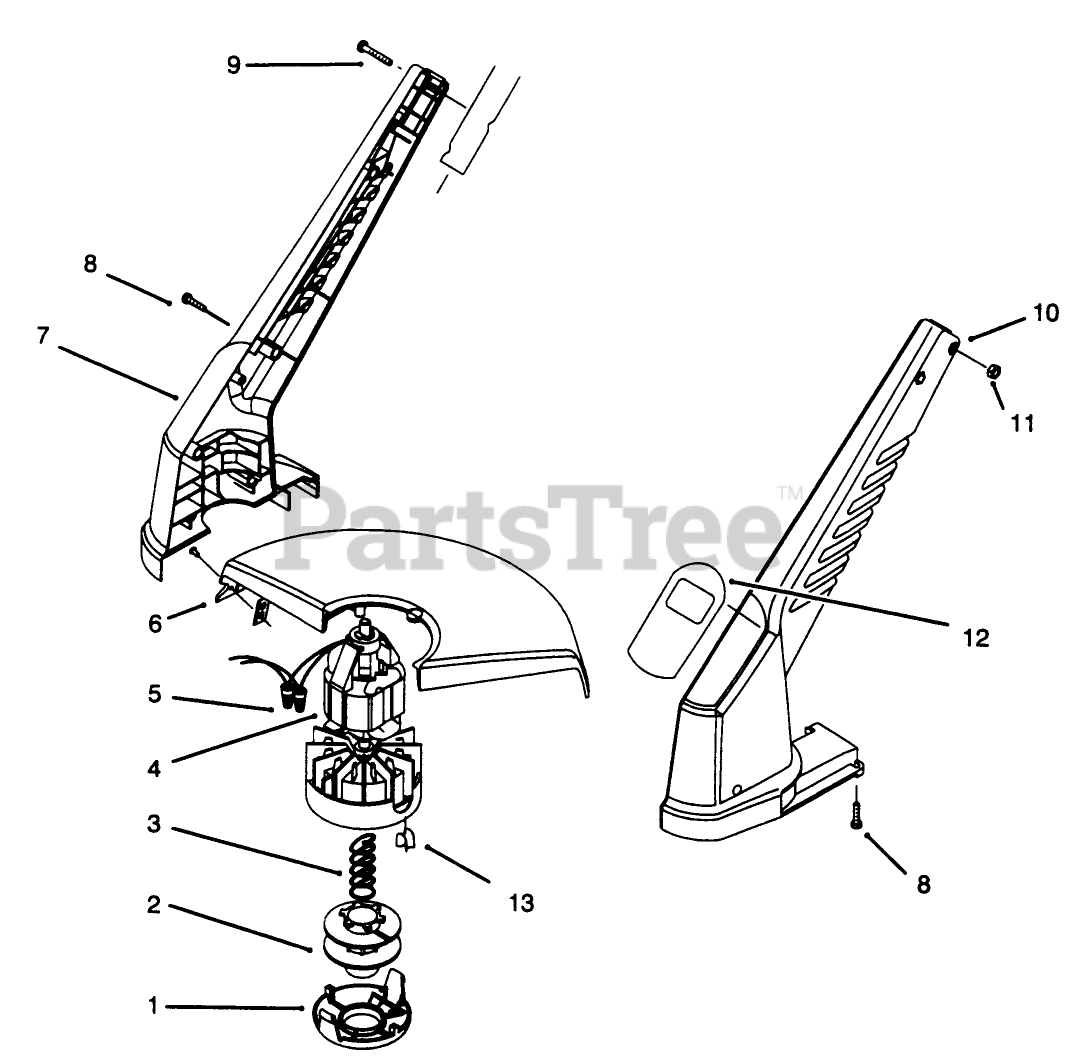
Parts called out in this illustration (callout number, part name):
2	SPOOL-LARGE
3	SPRING-COMPRESSION
4	Motor Assembly (Incl. Ref. #13)
5	CONNECTOR-NUT, WIRE
6	SHIELD ASM - SERVICE
7	RH HOUSING
8	Screw
9	SCREW-PPH
10	LH HOUSING
11	NUT-HEX
12	DECAL - 14" TRIMMER
13	EYELET
